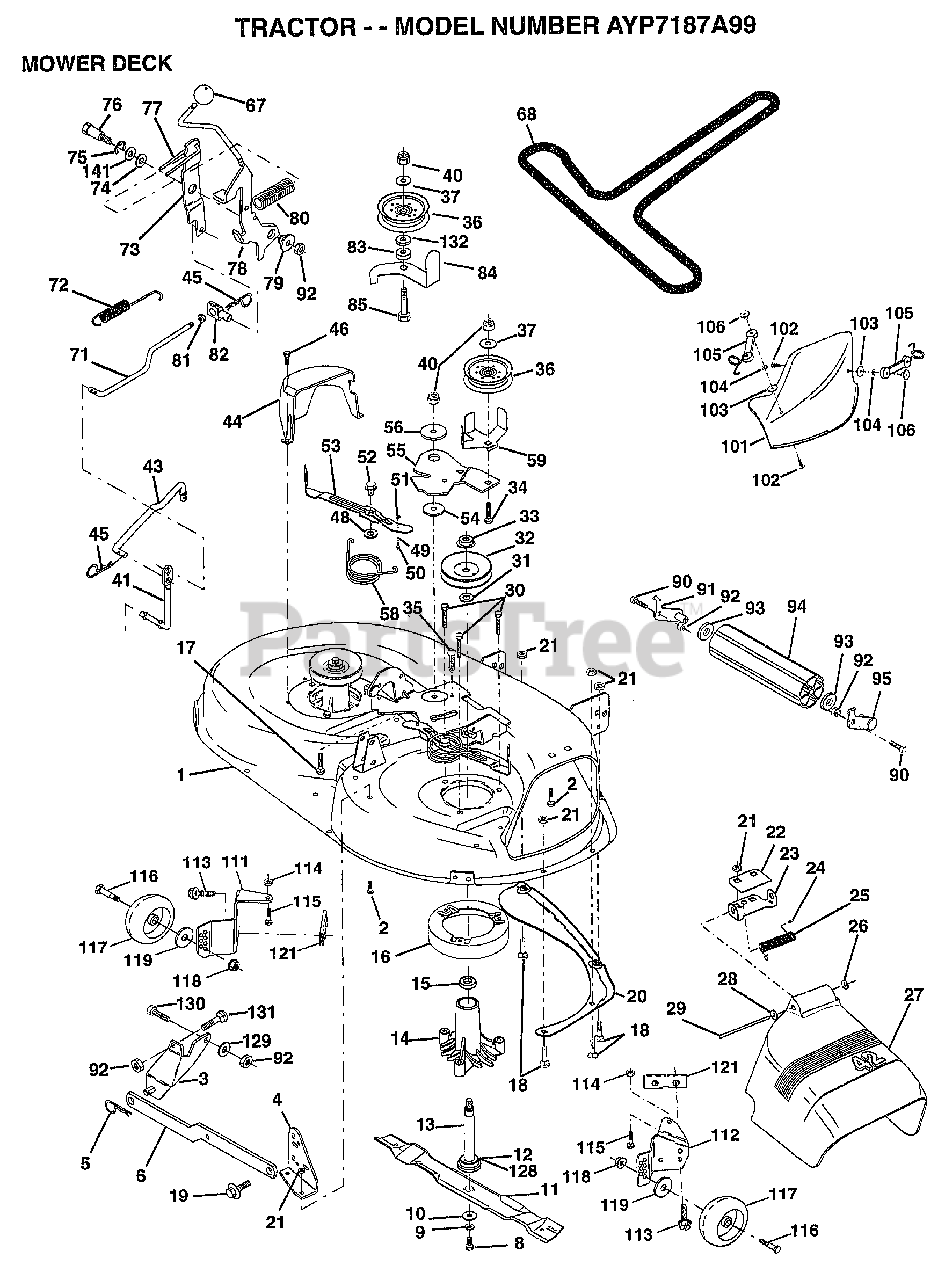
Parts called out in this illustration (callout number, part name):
1	"HOUSING ASSY.42"""
2	BOLT
3	BRKT ASM SWAY BAR
4	BRKT DECK SW BAR
8	BLADE BOLT
10	WASHER.HARD.BLADE
11	"BLADE.42"" MULCHER"
12	BEARING.BALL
14	HSG ASM MANDREL
15	BEARING
16	STRIPPER RND MWR
17	BOLT RDHD 3/8-16
18	BOLT
19	BOLT SHD 5/16-18
20	BAFFLE VORTEX 42
22	STIFFENER BRKT
23	DEFLECTOR BRKT
24	CAP-SLEEVE LT
25	SPRING TORSION
26	NUT PUSH M
27	DEFLECTOR.SHIELD
28	WASHER
29	HINGE ROD
30	"SCREW-THD ROLL,WA"
31	WASHER
32	PULLEY.MANDREL.42
34	BOLT
35	XMAS TREE FASTNER
36	FLAT IDLER PULLEY
37	WASHER
41	PIVOT ROD
43	ROD CLUTCH W/NIBS
44	GUARD MAND LH BLK
45	RETAINER M
46	SCREW.1/4-20X5/8
48	HARD SMALL WASHER
49	ROLLER ASM-CAM
50	SHOULDER BOLT
51	LOCKNUT
52	BOLT.SHLD.5/16-18
53	BRAKE PAD ARM ASM
54	HARDENED WASHER
55	ARM-IDLER
56	SPACER RETAINER
58	SPRING TORSN BRAK
59	GUARD IDLER TUV
67	KNOB.RD.7/16-14
68	BELT.V.T-PATH
71	ROD CLUTCH 38/42
72	RETURN SPRING
73	CLUTCH ARM SECOND
74	WASHER
75	RING
76	SHOULDER BOLT
77	SPRING KEEPER
78	LEVER.ASM.CLUTCH
79	BUSHING
80	SPRING.CLUTCH.MWR
81	NUT
82	TRUNION ADJ
83	WASHER
84	"KEEPER-BELT,FIXED"
85	BOLT
90	BOLT
92	NUT
93	WASHER
101	"COVER.MULCH.42"""
102	SCREW
103	WASHER #10
104	LOCKWASHER
105	LATCH ASSY.BAGGER
106	WELDNUT
111	BRACKET.GWHL.LH.
112	BRACKET.GWHL.RH.
113	SCREW
116	BOLT.SHOULDER
117	WHEEL GAGE DONUT
118	LOCKNUT
119	WASHER
121	BRACKET.EXTRD.GWL
128	WASHER.FELT.
129	WASHER
130	BOLT
132	WASHER GT
141	WASHER .T
